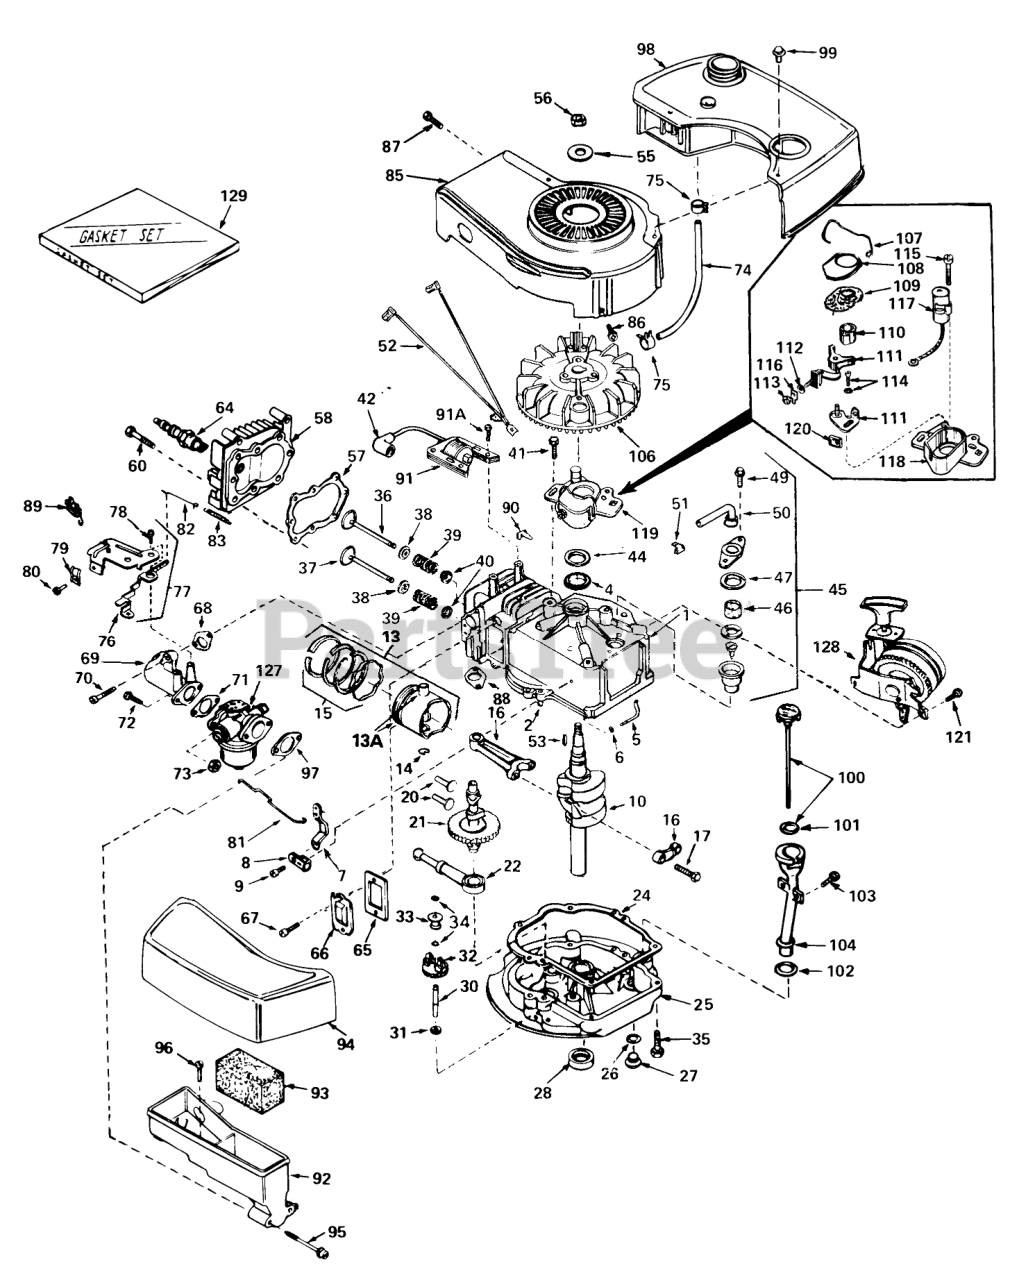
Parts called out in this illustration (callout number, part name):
1	Cylinder Assy. (Incl. Ref. #2, 4 & 121)
2	Pin-Dowel
4	Seal-Oil
5	Rod, Governor (Incl. Ref. #6)
6	Washer-Flat
7	Governor Lever
8	Clamp-Lever, Governor
9	Screw
10	Crankshaft
13	Piston, Pin & Ring Assy. (Incl. Ref. #13A, 14 & 15) (Std.)
13	Piston, Pin & Ring Assy. (Incl. Ref. #13A, 14 & 15) (.010 oversize)
13	Piston, Pin & Ring Assy. (Incl. Ref. #13A, 14 & 15) (.020 oversize)
13A	Piston & Pin Assy. (Incl. Ref. #14) (Std.)
13A	Piston & Pin Assy. (Incl. Ref. #14) (.010 oversize)
13A	Piston & Pin Assy. (Incl. Ref. #14) (.020 oversize)
14	Ring-Retaining, Piston Pin
15	Ring Set Piston (Std.)
15	Ring Set Piston (.010 Oversize)
15	Ring Set Piston (.020 Oversize)
16	Rod Assy., Connecting (Incl. Ref. #17)
17	Bolt-Rod, Connecting
20	Lifter-Valve
21	Camshaft(Mech.Comp. Release)
22	Oil Pump ASM
24	Gasket, Mounting
25	Flange Assy., Mounting (Incl. Ref. #26 thru 30)
26	Gasket-Oil Drain
27	Plug Oil Drain
28	Seal Oil
30	Shaft-Governor
31	Washer-Flat
32	Gear Assy. Governor (Incl. Ref. #31)
33	Spool-Governor
34	Ring-Retaining
35	Screw (1/4-20 x 1-1/4)
36	Valve Intake (Std.)(Incl. #38, 39 & 40)
36	Valve, Intake (1/32"oversize) (Incl. Ref. #38, 39 & 40)
37	Valve, Exhaust (Std.) (Incl. Ref. #38, 39 & 40)
37	Valve, Exhaust (1/32" oversize) (Incl. Ref. #38, 39 & 40)
38	Cap-Upper Valve Spring
39	Spring-Valve
40	Cap-Valve, Spring
42	Cover-Spark Plug
44	Gasket Stator
45	Breather Assy. (Incl. Ref. #46, 47, 49, 50 & 51 )
46	Element-Breather
47	Gasket-Breather
49	Screw (10-24 x 9/16)
50	Tube, Breaker
51	Clip, Breather
52	Wire Ground
53	682488 LB GRASS HI-
55	Washer-Belleville
56	Nut-Flywheel
57	63573 GIL 42 SNWTHW
58	Head-Cylinder
60	Screw (5/16-18x1-1/2)
64	Plug, Spark (J17LM or equiv.)
64	Plug, Spark (Champion RCJ-8)
65	Gasket-Breather
66	Cover-Valve
68	Gasket, Intake
69	Pipe, Intake
70	Screw (1/4-20 x 1)
71	Gasket-Carburetor
72	Screw (1/4-28 x 7/8)
73	Nut and Lock Washer (1/4-28)
74	Line-Fuel
75	Clamp-Line, Fuel
76	Lever Control
77	Control Assy., Speed (Incl. Ref. #76, 78 & 89)
78	Screw, Hex Washer Hd Shoulder Self-Tap
79	Conduit
80	Screw (10-32 x 3/8)
81	Link-Throttle
82	Link Governor Spring
83	Spring Governor
85	Housing Blower
86	Screw
87	Screw (10-24 x 9/16)
88	Gasket Exhaust
89	Terminal
90	Clip-Wire
91	Lamination & Coil Assy. (Incl. Ref. #42)
91A	Screw
92	Body Air Cleaner
93	Filer, Air
94	Cove, Air Cleaner
95	Screw Fil Hd.
96	Screw, Hex Hd.
97	Gasket-Air Cleaner
98	Tank, Fuel
99	Screw (10-32 x 35/64)
100	Dipstick, Oil (Incl. Ref. #101 ) (Twist Lock)
103	Screw (10-32 x 1/2)
104	Tube-Oil Fill
106	FIywheel
107	Spring Breaker Box
108	Cover-Dust
109	Gasket-Dust Cover
110	Cam-Breaker
111	Breaker Assy.
114	Breaker Screw
115	Condenser Screw
116	Terminal, Ground
117	Condenser
118	Stator Plate
119	Stator Assy. (Incl. Ref. #107, 111 thru 118 & 120)
120	Felt,Cam Wiper
121	Screw (1/4-20 x 1/2)
127	Carburetor (Incl. Ref. #71)
128	Starter, Side Mount
129	53024/VAR.16HP O/P
